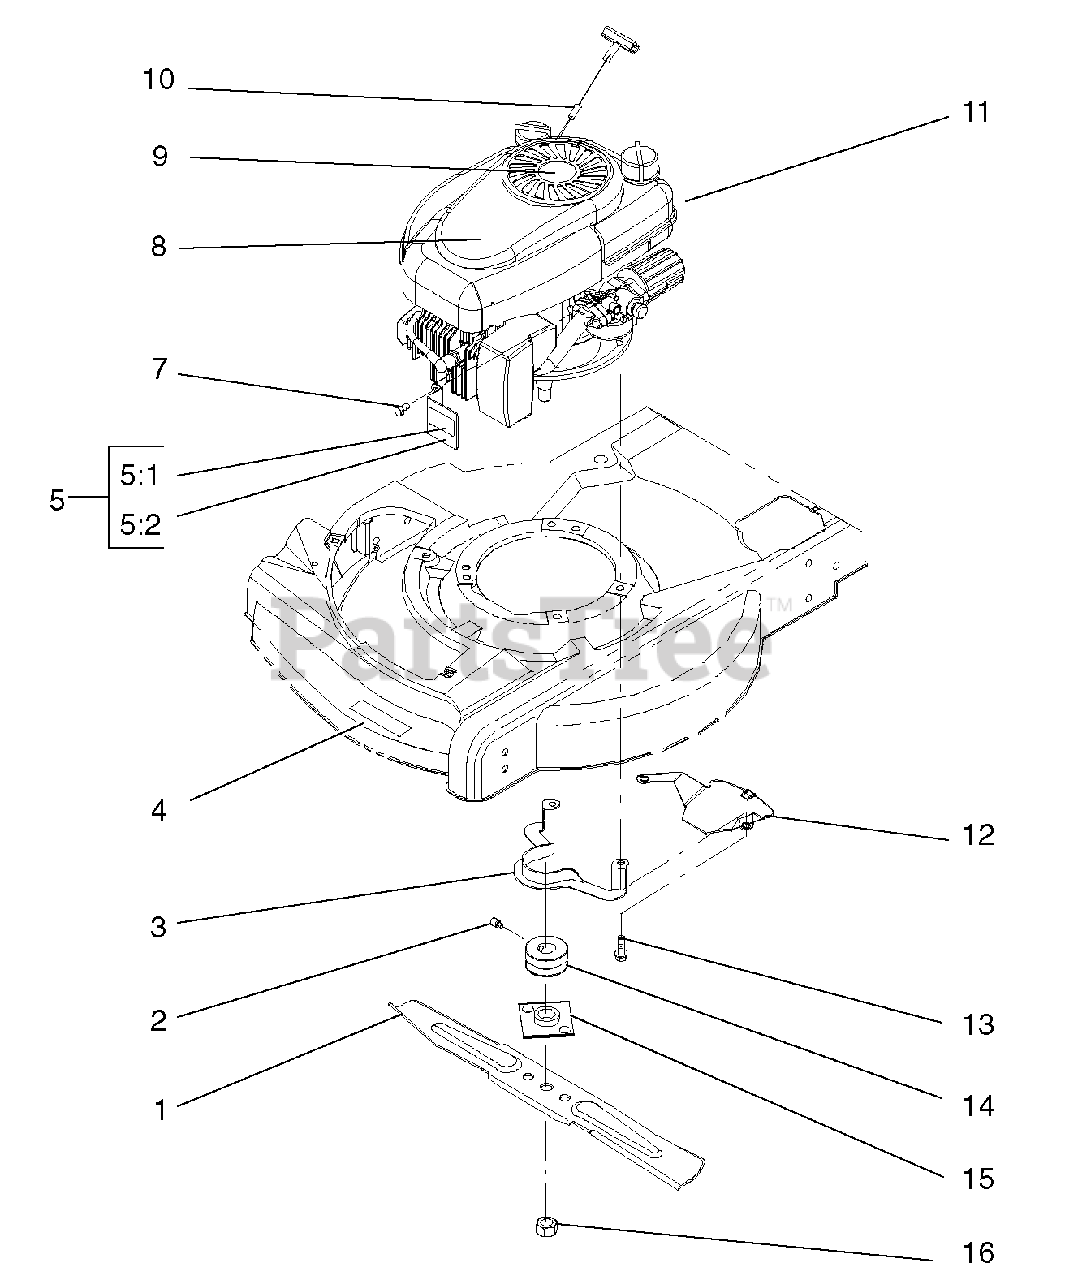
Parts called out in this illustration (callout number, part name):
2	Screw-Set
3	Guide-Belt
5	Muffler Guard ASM
5:1	Decal-Surface, Hot
5:2	Guard-Muffler
8	Applique
9	Decal-Recoil
10	Stop-Rope
12	Shield-Grass
13	Screw-Taptite W/Patch
15	Blade Retainer ASM
16	Nut-Blade
